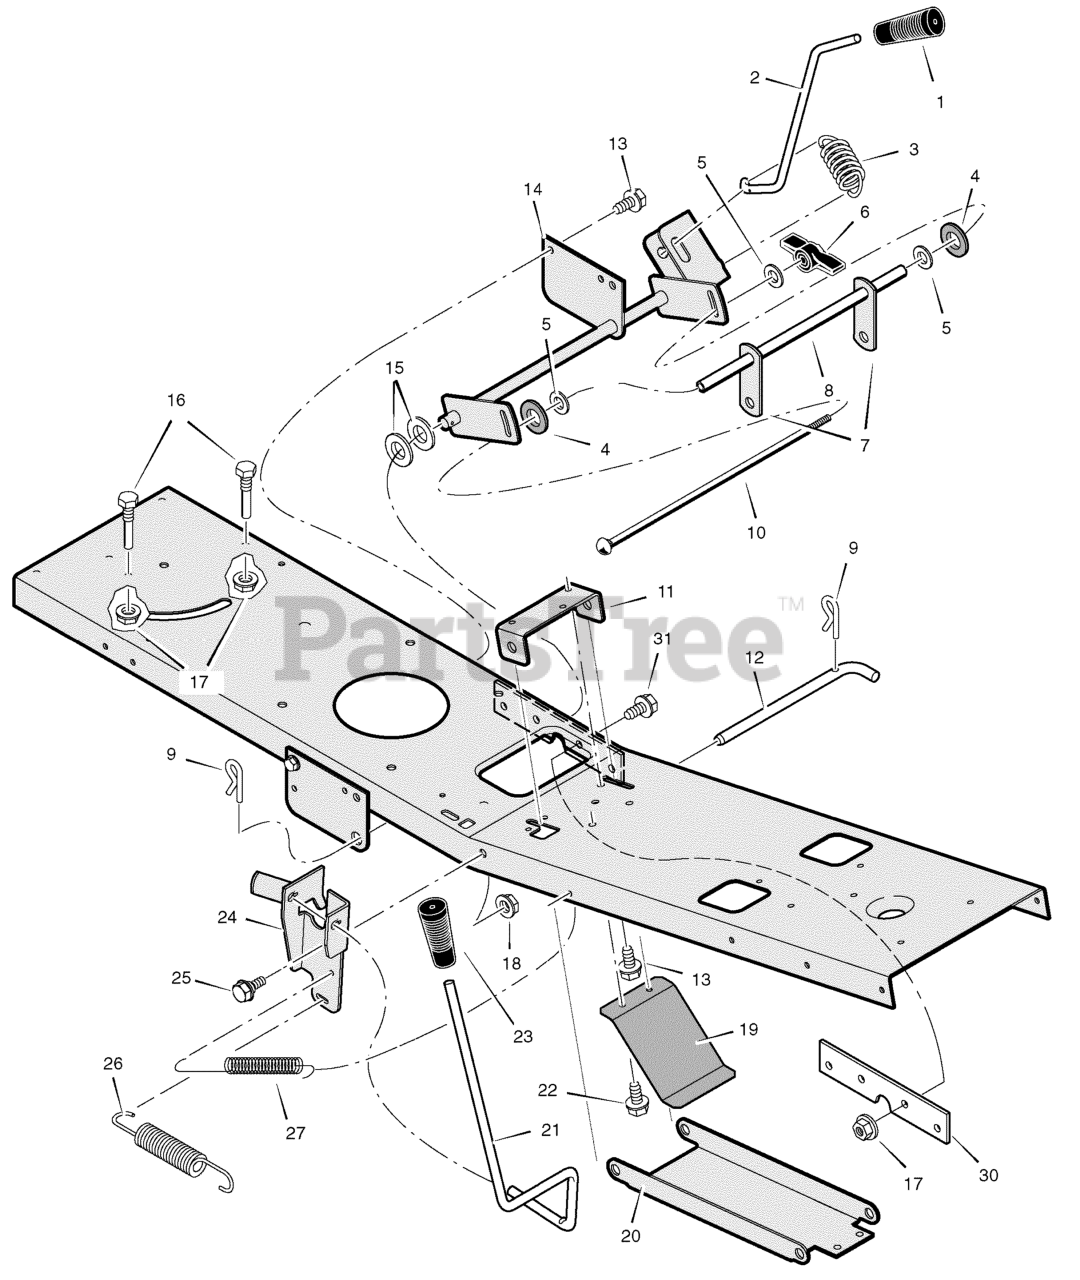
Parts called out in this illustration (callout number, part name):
1	Grip, Lift Lever
2	Lever, Lift
3	Spring, Extension
4	Pad, Friction
5	Washer
6	Wingnut
7	Link, Lift
8	Tube, Spacer
9	Pin, Hair
10	Bolt, Carriage
11	Bracket, Front Hanger Pivot
12	Pin, Front Hanger
13	Screw
14	Arm Assembly, Lifter
15	Washer
16	Screw, Guide
17	Nut, Flange
18	Nut, Flange
19	Spring, Leaf
20	Hanger, Front
21	Lever, PTO
22	Screw
23	Grip, PTO
24	Bracket, PTO
25	Bolt, Shoulder
26	Spring, Extension
27	Spring, Extension
30	Plate, Reinforcement
31	Screw
